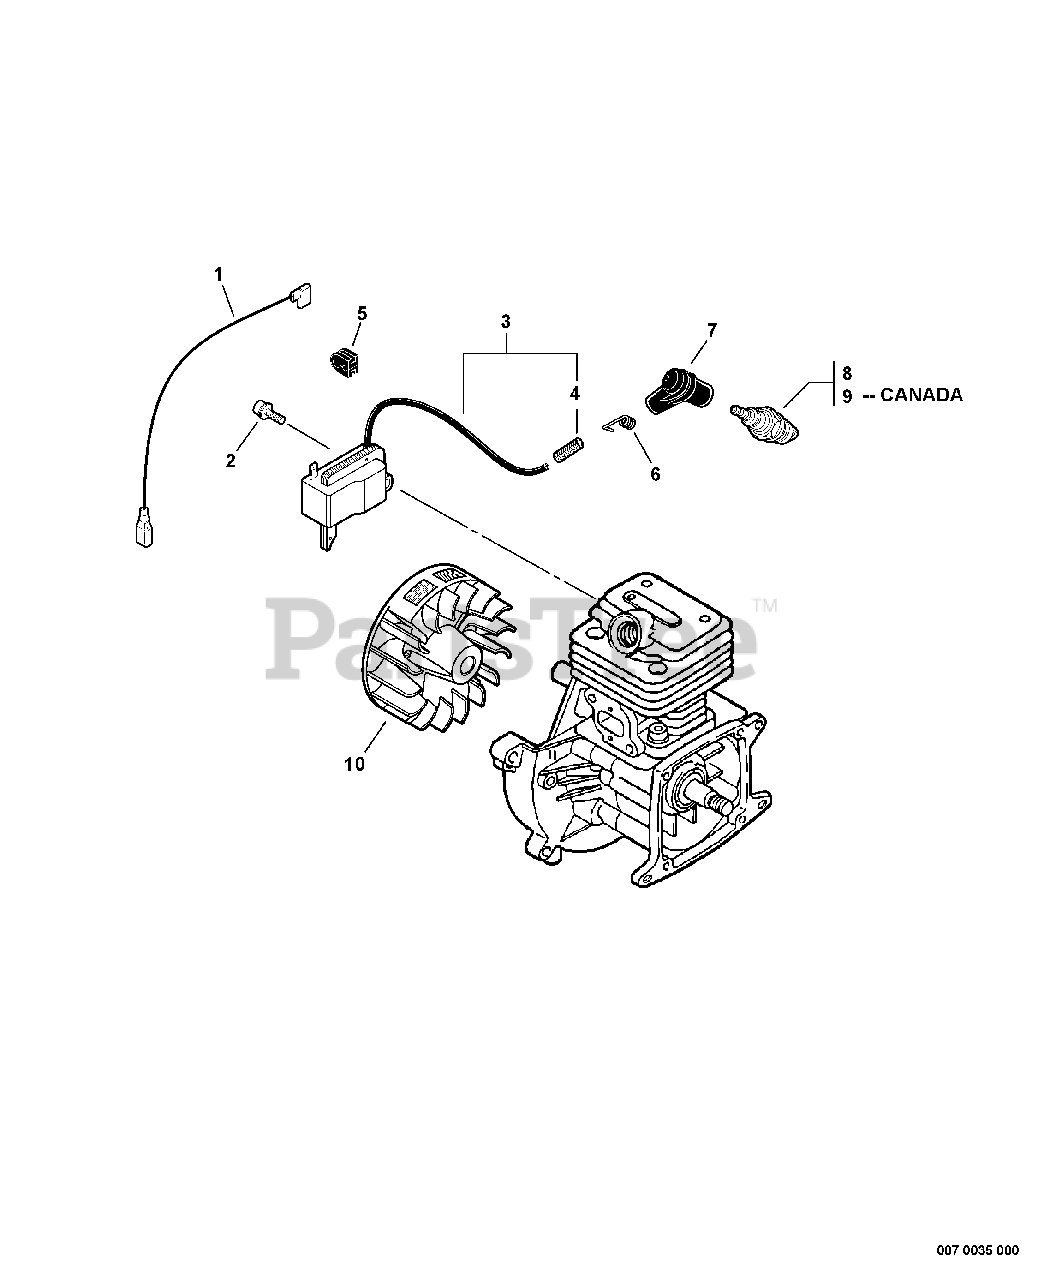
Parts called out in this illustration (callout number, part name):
1	LEAD - IGNITION
2	BOLT 5×16
3	COIL, IGNITION
4	TUBE, INSULATOR
6	TERMINAL, SPARK PLUG
7	CAP, SPARK PLUG
8	SPARK PLUG - BPM8Y
9	SPARK PLUG - BPMR8Y
10	FLYWHEEL
